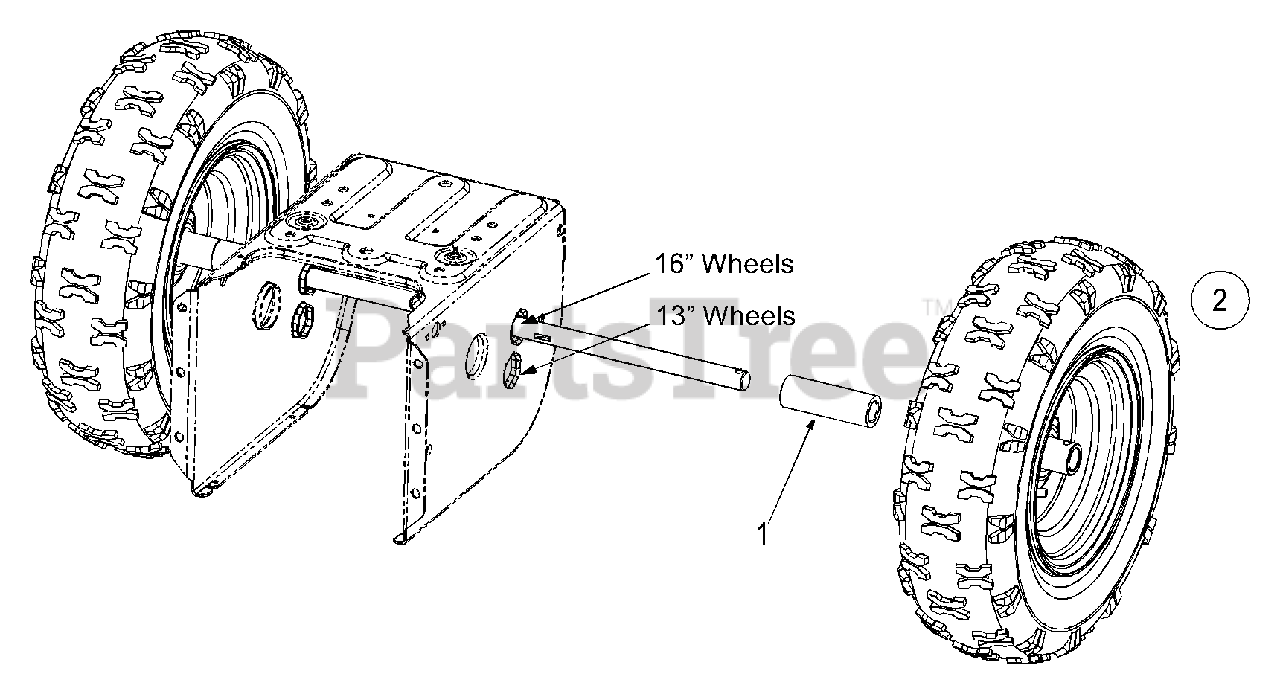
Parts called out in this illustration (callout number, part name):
1	13 x 4 Spacer
1	13 x 5 Spacer
1	16 x 4.8 Spacer
1	16 x 6.5 Spacer
1	15 x 5 Spacer
